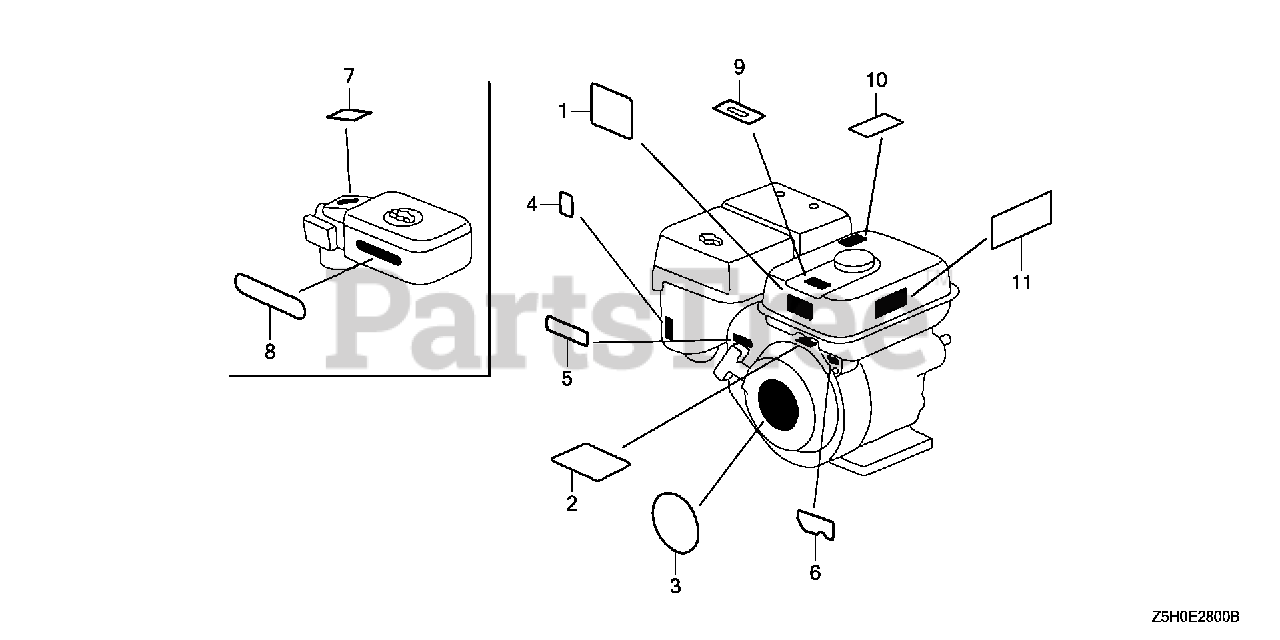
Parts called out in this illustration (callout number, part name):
2	MARK, OPERATOR CAUTION (ENGLISH)(MADE IN JAPAN)
3	EMBLEM (GX270 9.0)
3	EMBLEM (GX270)
4	MARK, CHOKE (GRAY)
5	MARK, THROTTLE INDICATION
10	MARK, EX. CAUTION (ENGLISH)
